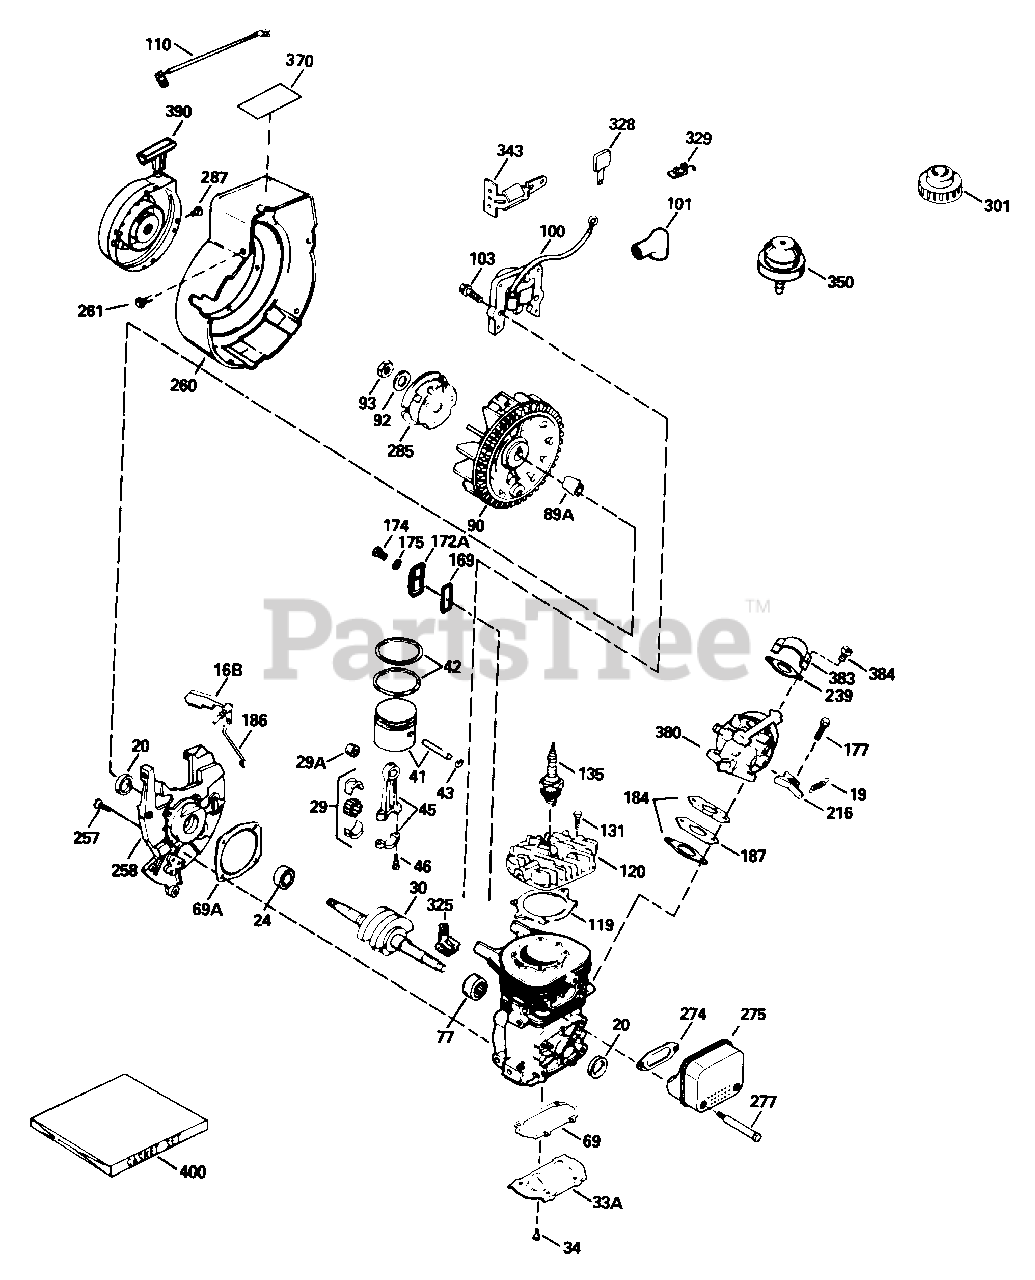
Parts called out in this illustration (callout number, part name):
16B	Vane Ass'y., Air
19	Spring, Governor
20	Seal, Crankshaft
24	Bearing, Ball (Mag. end)
29	Bearing & Liner Set, Needle
29A	Bearing, Cartridge
30	Crankshaft
33A	Plate, Cover
34	Screw (Cover Mounting) Int. Torx Hd., 10-24 x 1/2
42	Ring Set, Piston
43	Ring, Piston Pin Retaining
45	Rod Ass'y., Connecting
46	Screw, Connecting Rod
69	Gasket, Cover Plate
69A	Gasket, Housing Base
77	Bearing, Cartridge (PTO End)
89A	Sleeve, Keyed Adapter
92	Washer, Belleville
93	Nut, Flywheel
100	Solid State Ass'y.
101	Cover, Spark Plug
103	Screw (Solid State) Torx Hex Washer Hd. Sems, 10-24 x 1
110	Wire, Ground
119	Gasket, Cylinder Head
120	Head, Cylinder
131	Screw (Cylinder Head) Torx Pan Hd., 1/4-20 x 3/4
135	Plug, Spark
169	Gasket, Cover
172A	Cover Ass'y., Compression Release
174	Screw (Comp. Rel. Cover) Int. Torx Hd., 10-24 x 1/2
175	Washer, Flat (Comp. Rel. Cover)
177	Screw, 5/32 Hex Socket Button Hd. Cap, 1/4-20 x 1
184	Gasket, Carburetor
186	Link, Governor
187	Spacer (Carburetor)
216	Lever, Speed Adjusting
239	Gasket, Filter Base
257	Screw (Base Mounting) Torx Pan Hd., 1/4 x 5/8
258	Base Ass'y., Blower Housing
260	Housing, Blower
261	Screw (Blower Housing) Hex Wash. Hd. Taptite, 1/4-20 x 1/2
274	Gasket, Muffler
277	Screw, Hex Hd., 1/4-20 x 2-3/4
285	Cup, Starter
287	Screw, Hex Washer Hd., 8-32 x 1/2
301	Cap Ass'y., Fuel
328	Key
329	Terminal Ass'y.
343	Bracket, Key Switch
350	Primer Ass'y.
370	Decal, Caution
380	Carburetor
383	Baffle, Air
384	Screw, Torx Pan Hd. Sems, 10-32 x 3/8
390	Starter, Rewind
400	Gasket Set
